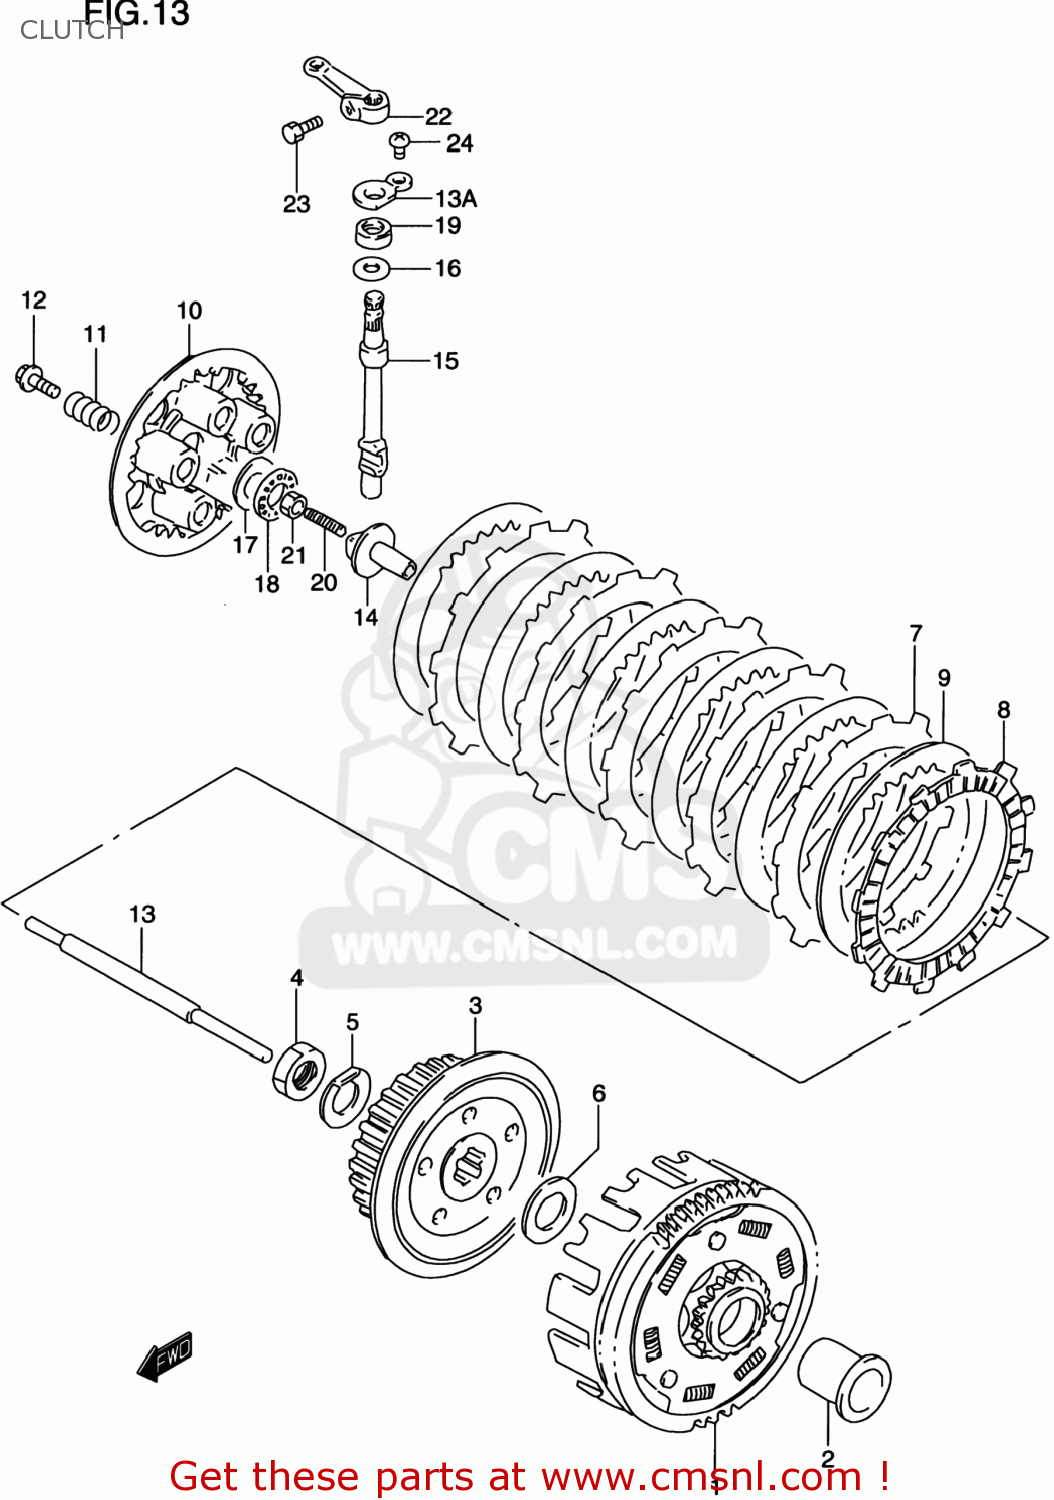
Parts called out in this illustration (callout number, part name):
1	GEAR ASSY,PRI DRIVEN
2	SPACER,PRIMARY DRIVEN GEAR
3	HUB,CLUTCH SLEEVE
4	NUT
5	WASHER
6	WASHER
7	PLATE,CLUTCH DRIVE (NAS)
8	PLATE,CLUTCH DRIVE(T:3.0) (NAS)
9	PLATE,DRIVEN(T:1.4)
10	PLATE,CLUTCH PRESSURE
11	SPRING
12	BOLT 5X16
13	ROD,CLUTCH PUSH
13A	RETAINER,CL RLSE OIL SEAL
14	PIECE,CLUTCH PUSH
15	CAMSHAFT,CLUTCH RELEASE
16	WASHER,THRUST
17	WASHER(15.5X28X1)
18	BEARING(15X28X2)
19	SEAL,OIL(10X20X6)
20	SCREW(6X25)
21	NUT
22	ARM,CLUTCH RELEASE
23	BOLT
24	SCREW 6X10
